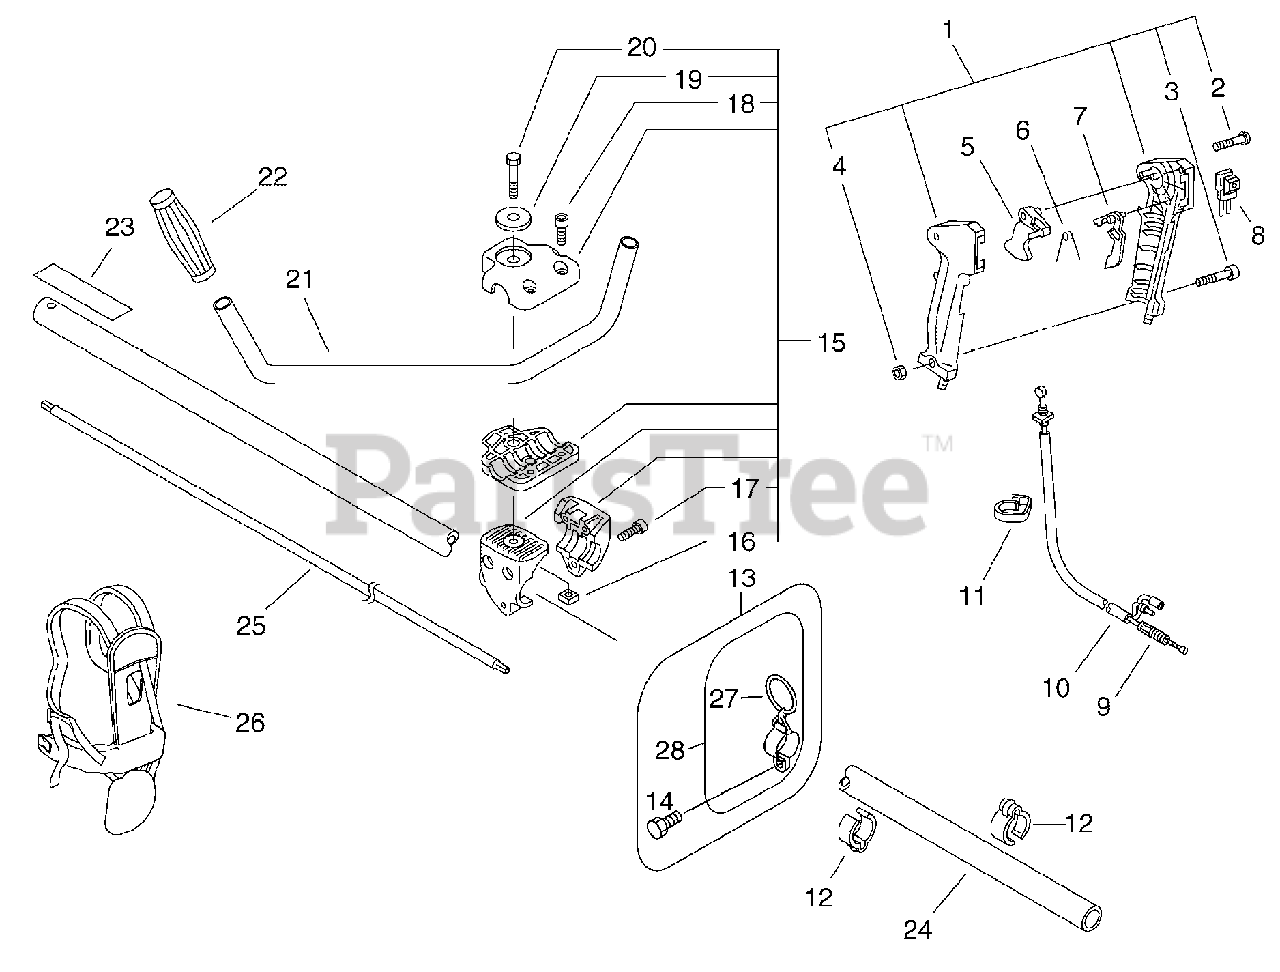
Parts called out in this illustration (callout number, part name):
1	HANDLE GRIP ASSY - FRONT
2	SCREW - 3X25
3	SCREW - 5X30
5	TRIGGER, THROTTLE
6	SPRING, LOCKOUT LEVER
7	LOCKOUT, THROTTLE
8	IGNITION SWITCH ASSY
9	CABLE, THROTTLE
10	TUBE, PROTECTIVE - CORRUGATED
13	HANGER ASSY
14	SCREW - 5X12
15	HANDLE BRACKET KIT
17	SCREW - 5X30
18	SCREW - 5X20
19	WASHER - 8
20	BOLT - 8X55
21	HANDLE - FRONT
22	GRIP, HANDLE
23	LABEL - CAUTION
24	PIPE, MAIN
25	DRIVESHAFT
28	HANGER KIT
